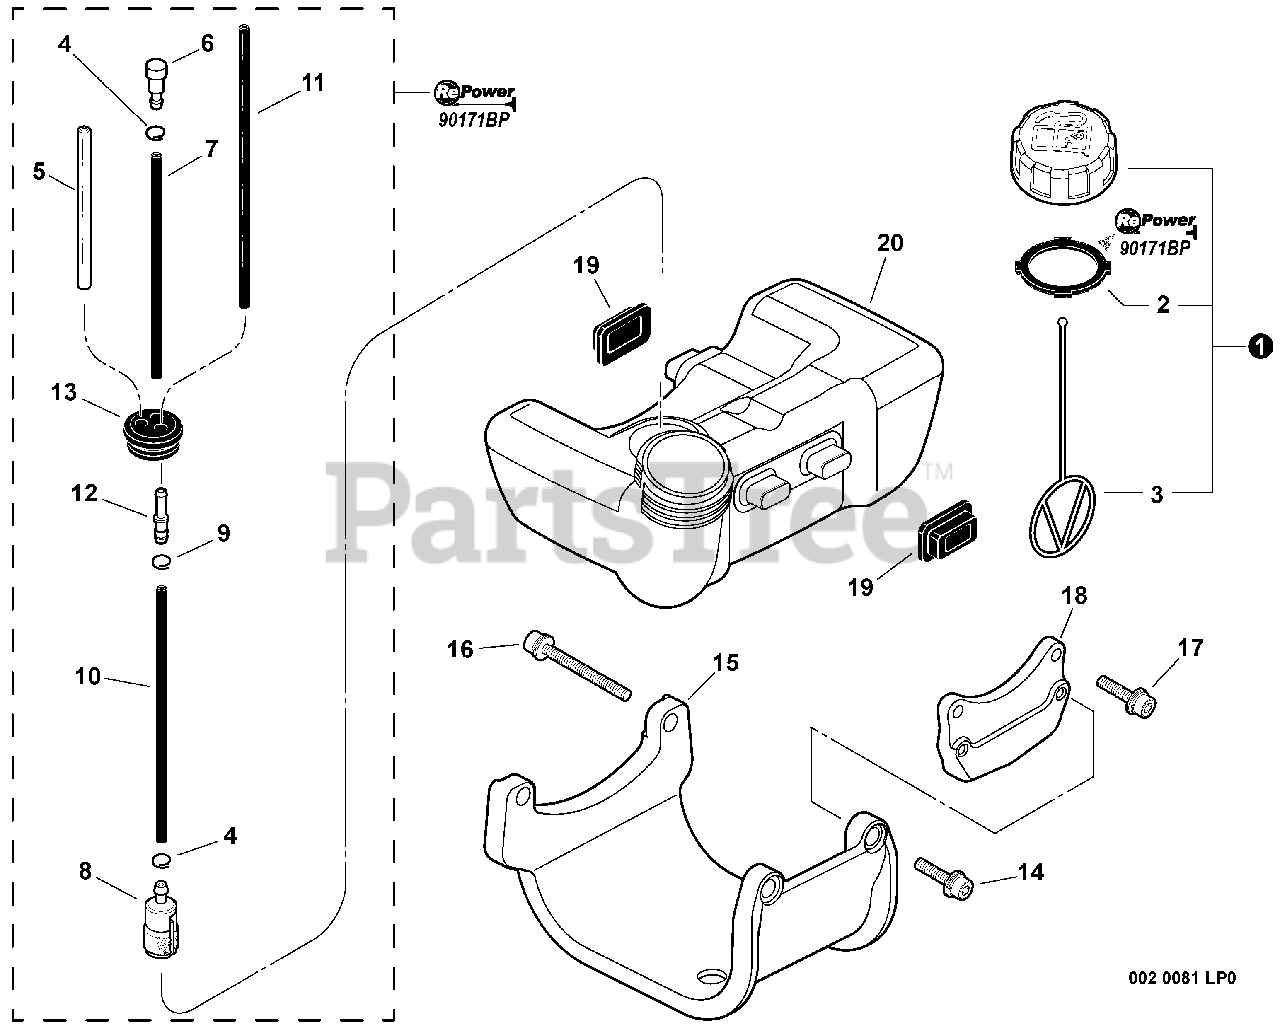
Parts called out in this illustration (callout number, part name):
1	CAP ASSY - RED
2	GASKET, CAP
3	CONNECTOR, CAP
4	CLIP - 6
5	PIPE - 3X6X90 -- CLEAR
6	VENT, FUEL TANK
7	PIPE - 3X6X115 -- BLACK
8	FILTER, FUEL
9	CLIP - 6.5
10	PIPE - 3X6X120 -- BLACK
11	PIPE - 3X5X78 -- BLACK
12	CONNECTOR, PIPE
13	GROMMET
14	SCREW - 5X20
15	SCREW - 5X40
16	GUARD, FUEL TANK
17	SCREW - 5X20
18	BRACKET
19	CUSHION, FUEL TANK
20	TANK, FUEL
21	RePower FUEL SYSTEM KIT
